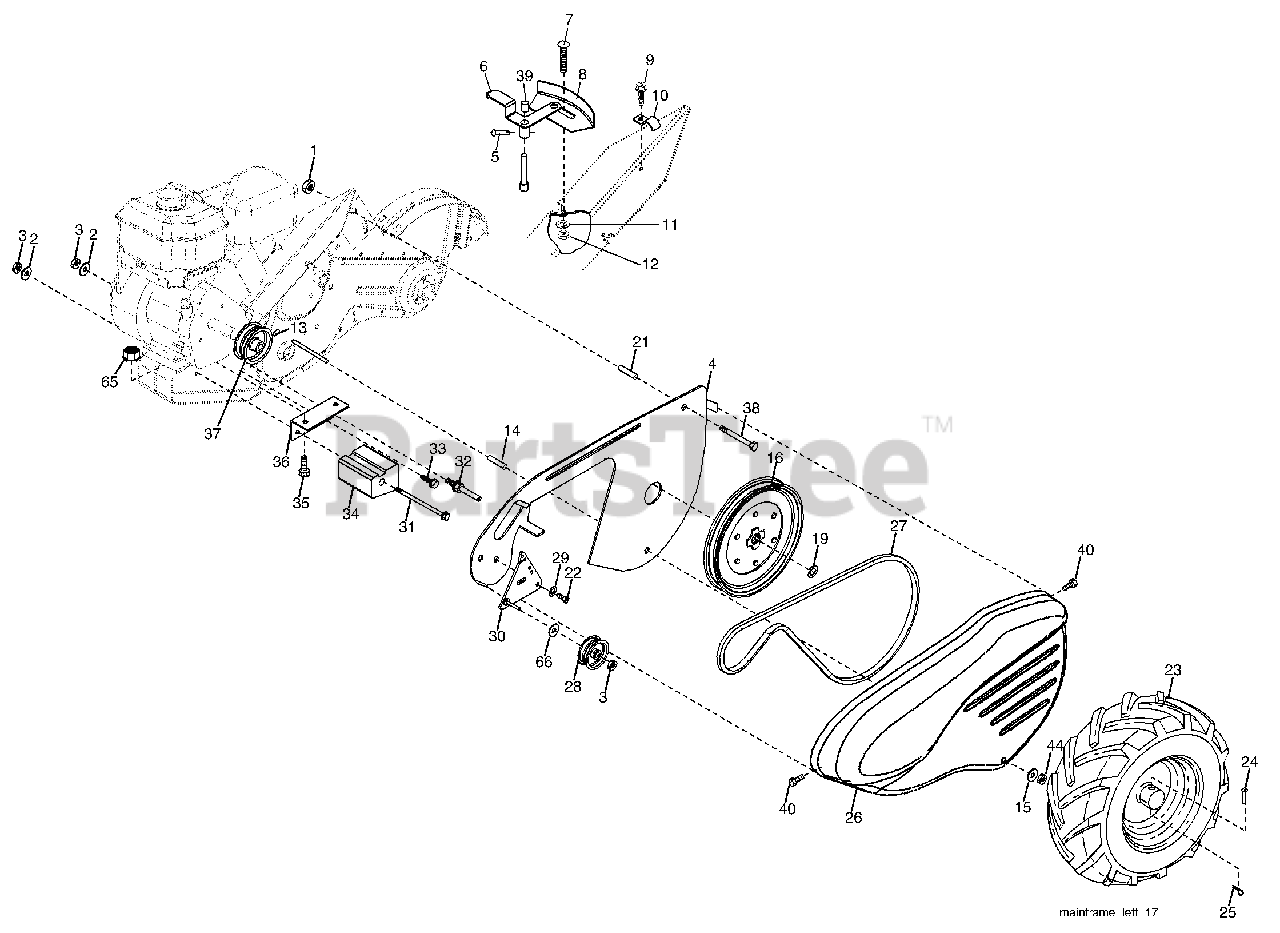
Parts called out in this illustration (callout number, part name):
1	Nut, Keps 5/16-18
2	Washer, Lock 3/8
3	Nut, Hex 3/8-16
4	Shield, Inner, Belt Guard
5	Pin Spirol Flared
6	Lever, Shift
7	Bolt, Carriage 1/4-20 x 1/2 Gr. 5
8	Plate, Shift Indicator
9	Screw, Hex, Washer Head, Slotted #10-24 x 1/2
10	Clip
11	Washer, Lock 1/4
12	Nut, Hex 1/4-20
13	Screw, Set, Hex 5/16-18 x 3/8
14	Spacer, Split 0.327 x 0.42 x 1.220
15	Washer 11/32 x 11/16 x 16 Ga.
16	Sheave, Transmission
19	Ring, Retainer
21	Spacer, Split 0.327 x 0.42 x 2.09
22	Bolt Hex 5/16-24 x 1/2
23	Tire
23	Rim
23	Tire Valve
24	Rivet, Drilled
25	Clip, Hairpin
26	Guard, Belt
27	Belt, V
28	Pulley, Idler
29	Ring, Klip
30	Bracket, Idler
31	Bolt, Hex 5/16-16 x 12
32	Shaft, Idler Arm
33	Bolt, Hex 3/8-16 x 1
34	Counterweight, L. H.
35	Bolt, Hex 5/16-18 x 1-1/2
36	Bracket, Reinforcement, L. H.
37	Sheave, Engine
38	Bolt, Hex 5/16-18 x 2-3/4
39	Cap, Plunger
40	Screw, Hex Wsh Slt #10-24 x .50
44	Nut, Lock 5/16-18
65	Nut, Lock Hex Flange
66	Washer
